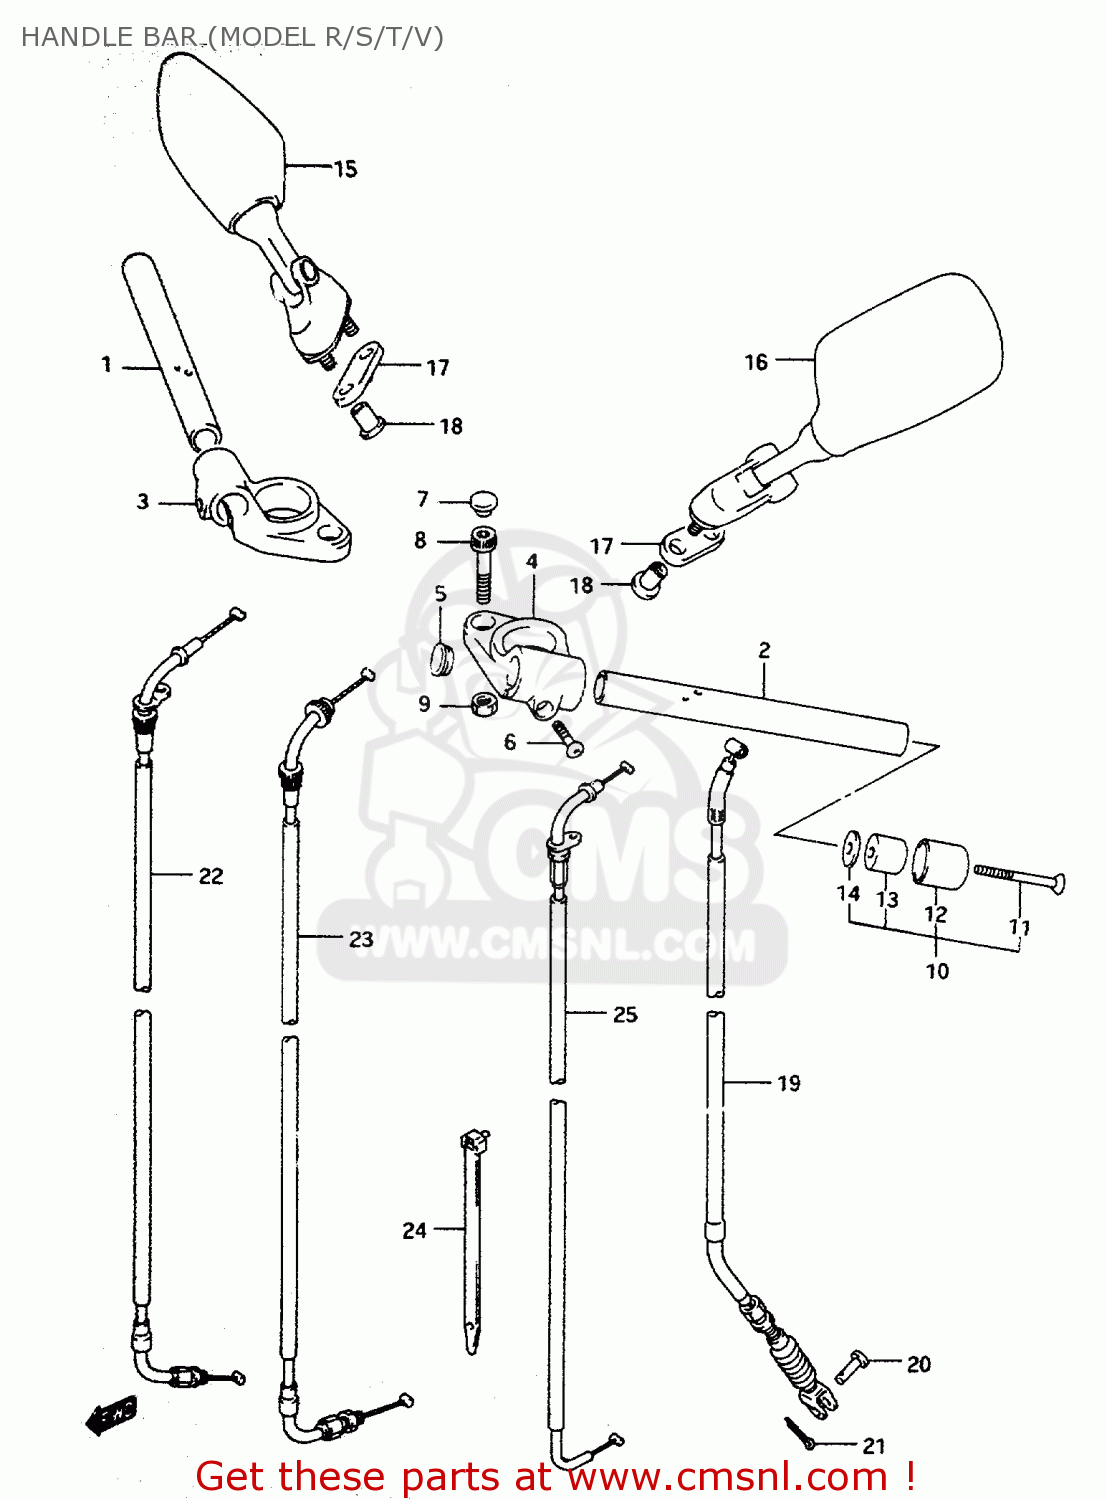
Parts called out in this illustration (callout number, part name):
1	HANDLEBAR
2	HANDLEBAR,L
3	HOLDER,HANDLEBAR,R
4	HOLDER,HANDLEBAR,L
5	PLUG(OD:22)
6	BOLT(8X25)
7	CAP(OD:12)
8	BOLT 10X50
9	NUT
10	BALANCER SET,HANDLEBAR
11	SCREW
12	CAP,BALANCER
13	BALANCER,HANDLEBAR
14	SPACER,BALANCER
15	MIRROR ASSY,RR VIEW,R
16	MIRROR ASSY,RR VIEW,L
17	CUSHION,RR VIEW MIRRORR
18	NUT,RR VIEW MIRROR
19	CABLE ASSY,CLUTCH
20	PIN(L:15)
21	PIN
22	CABLE ASSY,THROTTLE NO.1
23	CABLE ASSY,THROTTLE NO.2
24	CLAMP
25	CABLE COMP,STARTER
